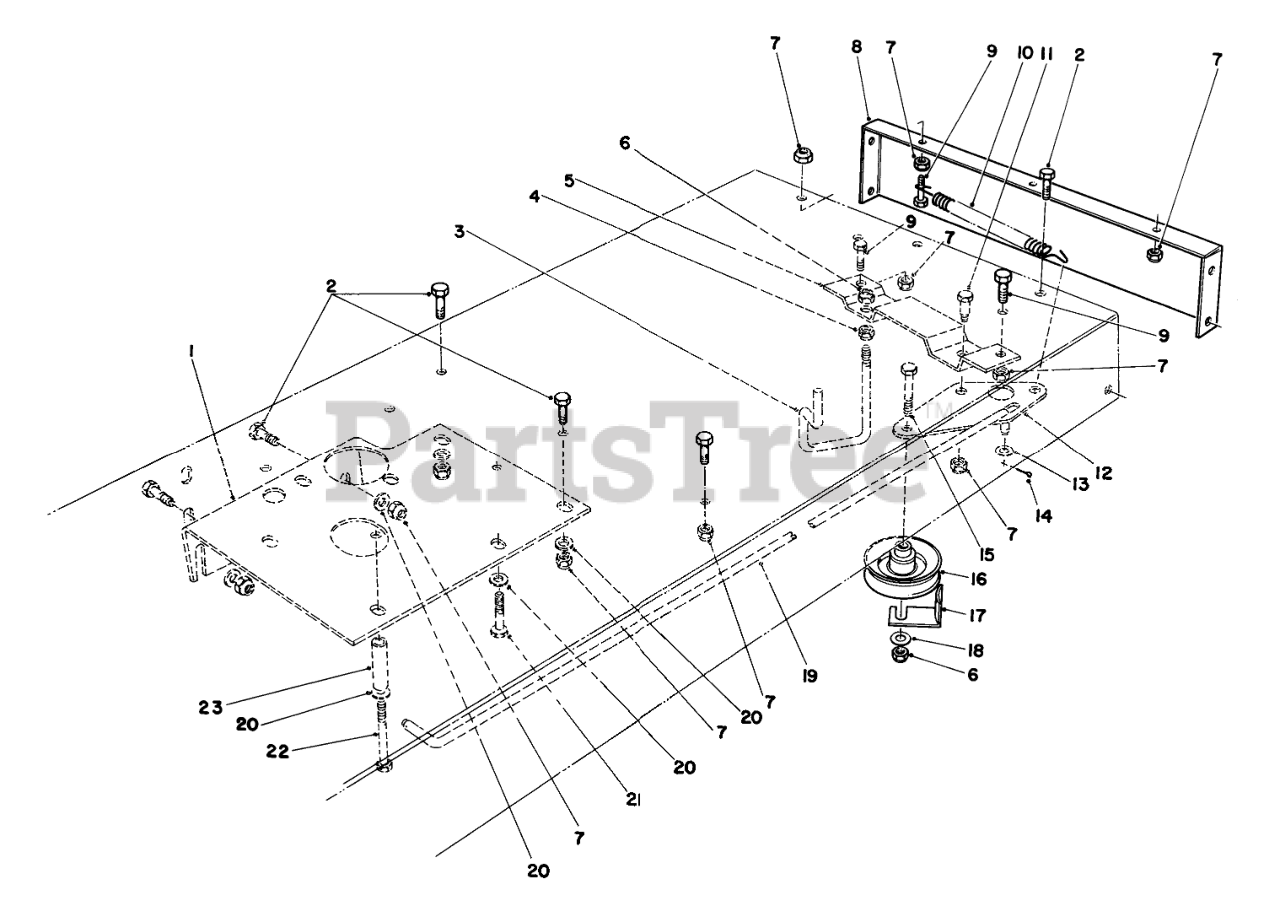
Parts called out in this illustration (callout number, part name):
1	REINF PLATE R
2	SCREW-HH
3	BELT GUIDE
4	NUT-LOCK, SIDE
5	TRACT SUPP BRKT B
6	NUT-LOCK, CONE
7	NUT-LOCK, NI
8	REAR FRAME R
9	SCREW-HH
10	TRACTION SPRING
11	BOLT-SHOULDER
12	TRACTION PIVOT BRKT
13	WASHER-FLAT
14	PIN-COTTER
15	SCREW-HH
16	PULLEY-IDLER
17	RETAINER-BELT
18	WASHER-FLAT
19	TRACTION ROD
20	WASHER-PLAIN
21	Screw-HH
22	SCREW-HH
23	OUTER TUBE SPACER
